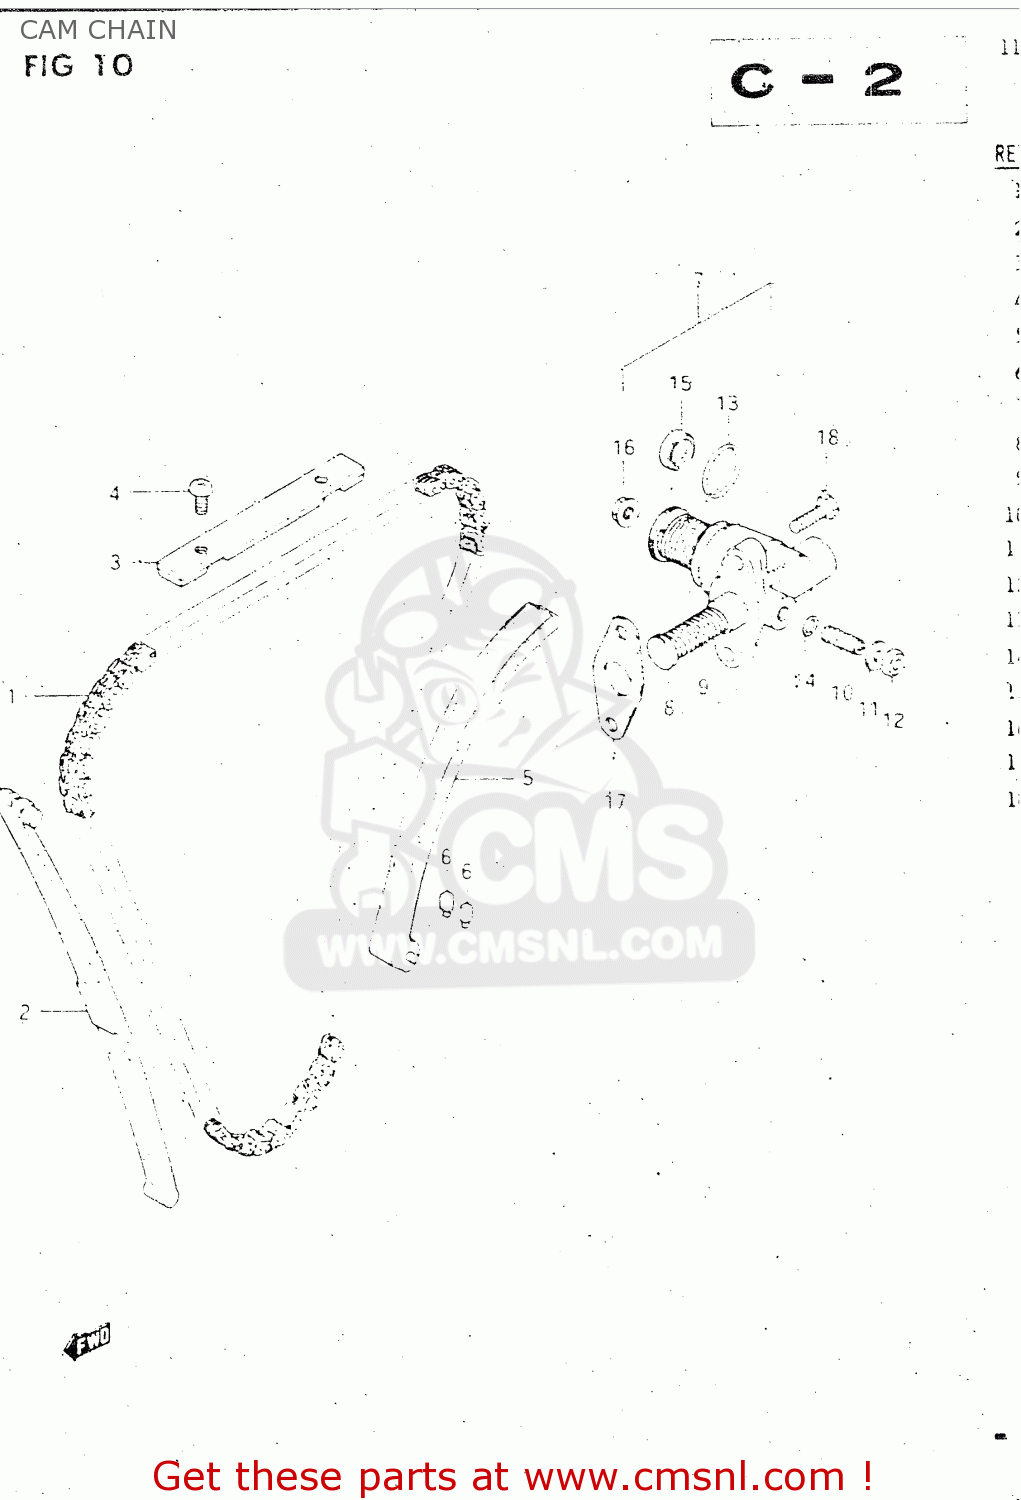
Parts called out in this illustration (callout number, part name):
1	CHAIN,CAMSHAFT DRIVE
2	GUIDE,CAM CHAIN NO.1
3	GUIDE,CAM CHAIN NO.2
4	SCREW
5	TENSIONER,CAM CHAIN
6	CUSHION,CAM CHAIN TENSIONER
7	ADJUSTER ASSY,TENSIONER
8	ROD,PUSH
9	SPRING
10	SCREW,TENSIONER ADJUST
11	WASHER,8.5X16X
12	NUT
13	O RING(D:2.4,ID:20.8)
14	O RING(D:1.9,ID:5.7)
15	SEAL,OIL(10X16X4)
16	NUT 6MM
17	GASKET,TENSIONER ADJUSTER (MCA)
18	SCREW
